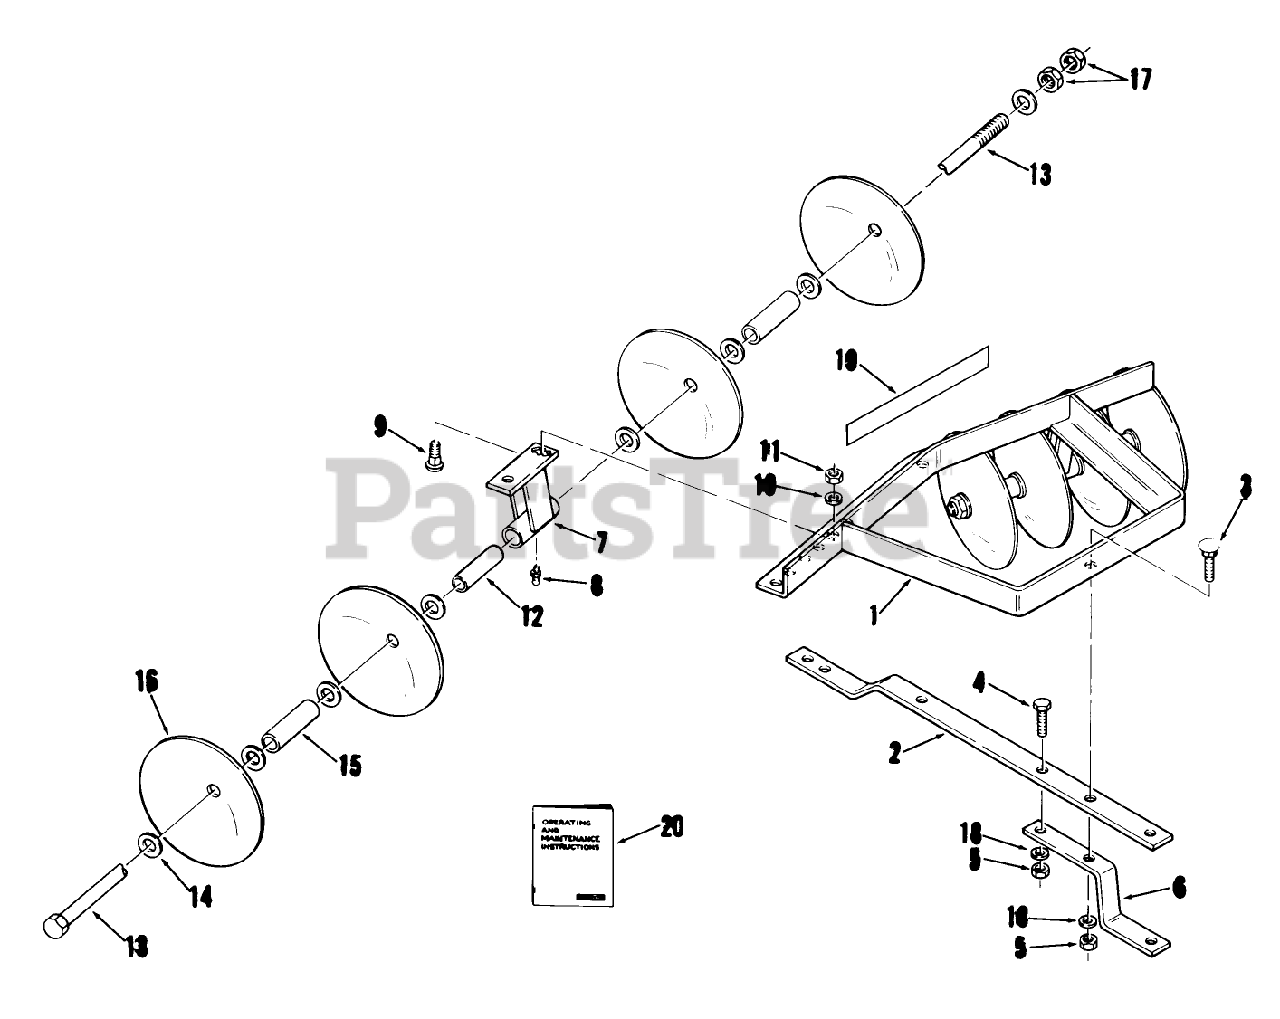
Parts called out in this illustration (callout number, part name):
1	Frame Assembly
2	Hitch Bar
3	CARRIAGE BOLT -4
4	Hhcs
5	Eslok Nut
6	Coupler Adapter
7	Bearing Hanger Assembly
8	Grease Fitting
9	Bolt
10	LOCKWASHER
11	Nut
12	Bearing
13	Bolt 3/4-10 X 16
14	Washer
15	Tube
16	BLADE DISC
18	Lockwasher
19	DECAL-WHEEL HORSE
20	Operating and Maintenance Instructions
